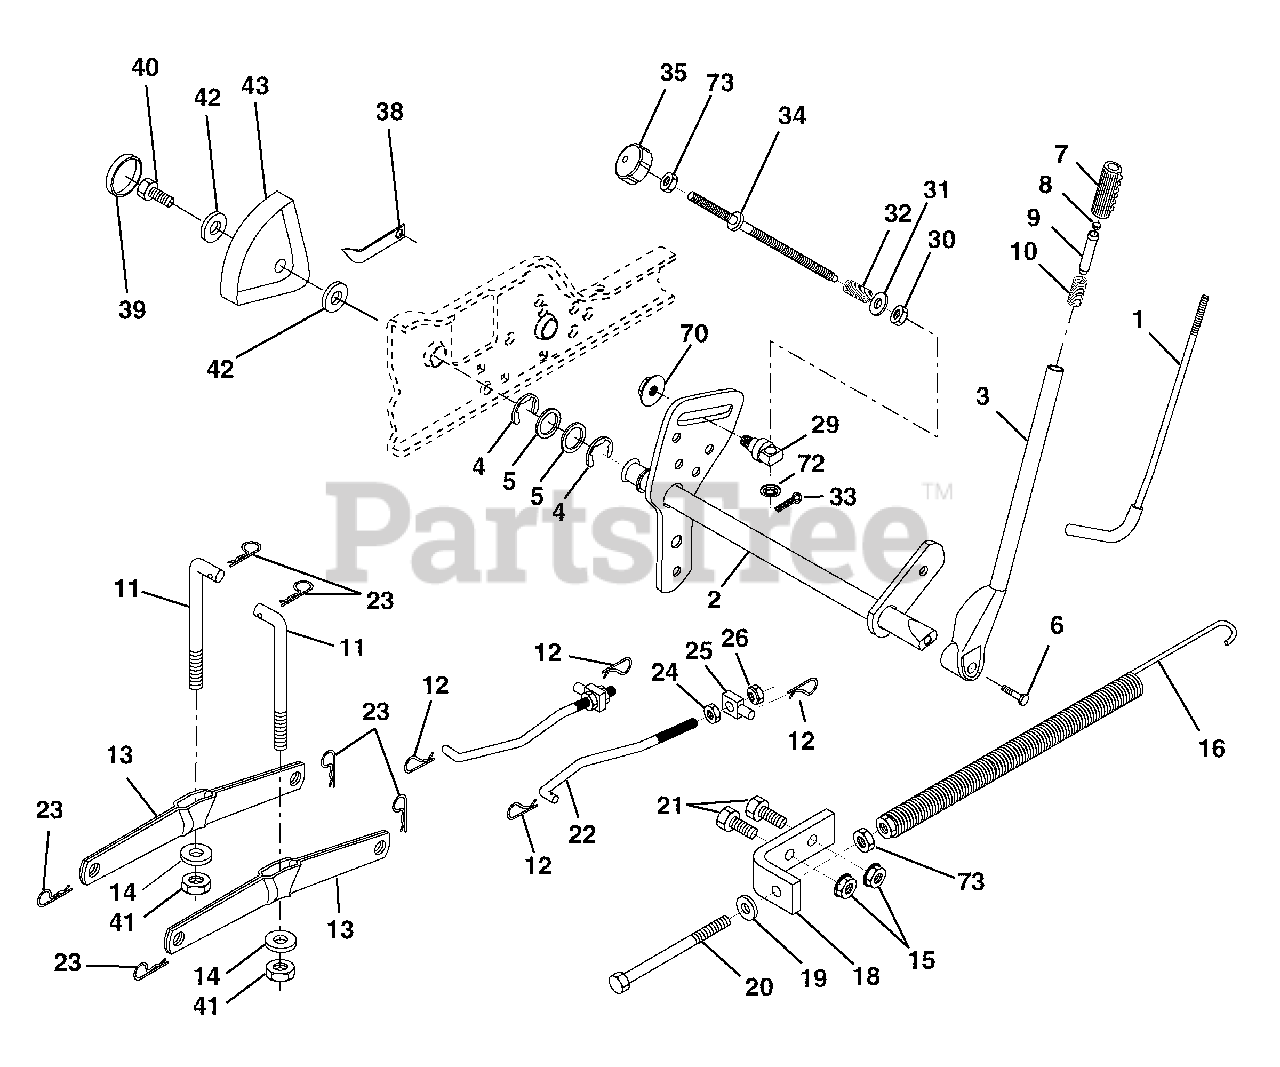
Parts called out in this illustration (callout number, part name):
1	Rod Asm., Lever
2	Shaft Asm., Lift Vgt
3	Lever Asm., Lift Rh
4	E-Ring Truarc #5133-87
5	Washer 29/32 x 1-1/4 x 16 Ga.
6	Bolt, Fin Hex 3/8-16 x 1-1/2
7	Grip,Handle
8	Button, Plunger
9	Plunger, Lever Lift
10	Spring 2-1/8"
11	Link Lift
12	Retainer,Spring
13	Arm, Suspension Vgt
14	Bearing
15	Nut, Crownlock 3/8-16
16	Spring Asm., Assist Lift
17	Nut, Hex Jam 3/8-16 Unc
18	Bracket, Spring Assist
19	Washer 13/32 x 13/16 x 16 Ga.
20	Bolt, Adjust Spring Assist
21	Bolt, Fin Hex 3/8-16 x 1
22	Link, Front
23	Retainer,Spring
24	Nut, Jam Hex 1/2-13 Unc
25	Trunnion
26	Nut, Lock W/Wsh 1/2-13 Unc
29	Trunnion Infin Height
30	Nut, Special
31	Washer 13/32 x 5/8 x 16 Ga.
32	Spring, Compression Inf Hgt
33	Pin, Cotter 3/32 x 1/2
34	Rod, Adj Lift
35	Knob, Inf 3/8-16 Unc
38	Pointer Height Indicator
39	Plug, Hole Blk. 1.485/1.515 Dia.
40	Screw Thdrol 5/16-18 x 3/4
41	Nut, Crownlock 3/8-24
42	Washer 11/32 x 1-1/2 x 10 Ga.
43	Scale, Indicator Height
70	Nut Hex Flange Lock
72	Nut Push Phos & Oil
